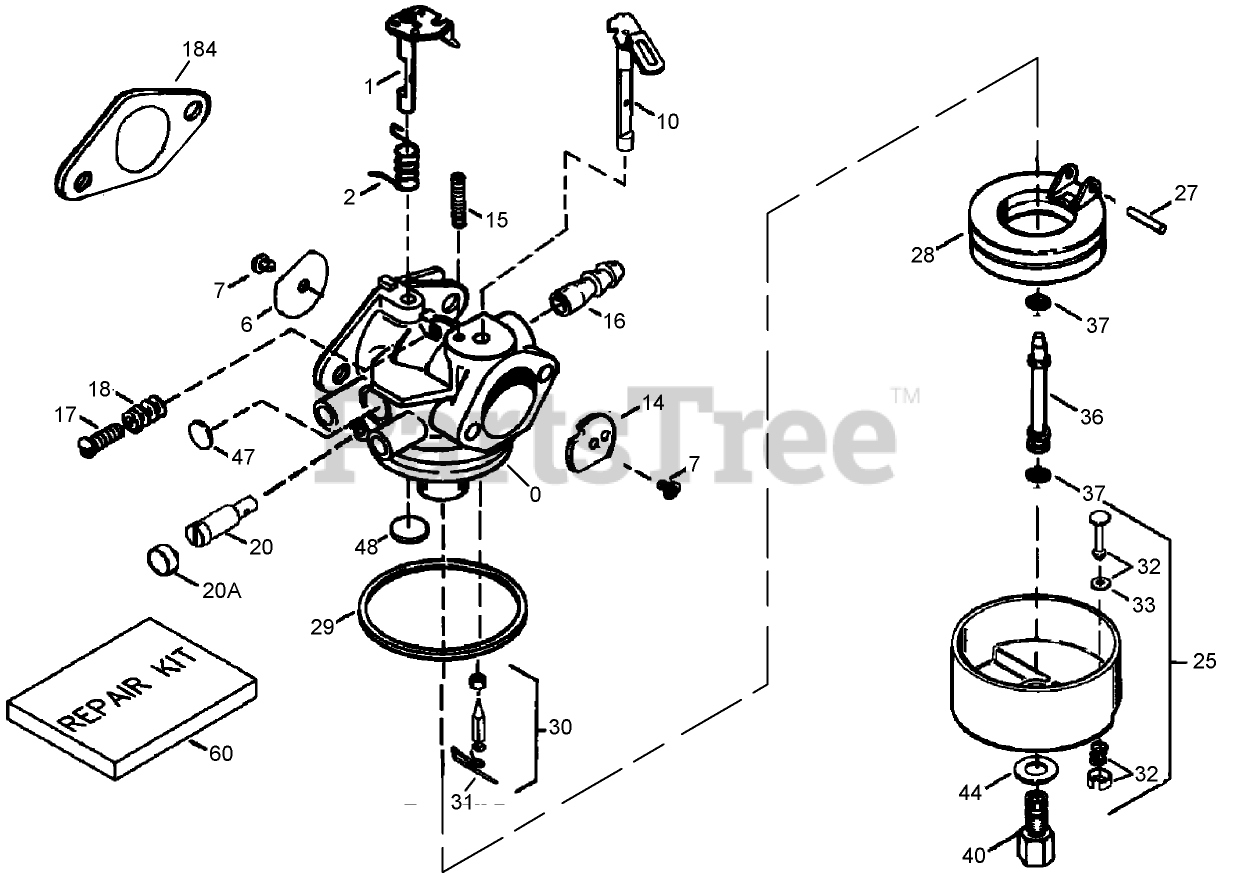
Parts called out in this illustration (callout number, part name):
1	Throttle Shaft and Lever ASM
2	Spring-Return, Throttle
6	Shutter-Throttle
7	Screw-Shutter
10	Choke Shaft and Lever ASM
14	Shutter-Choke
15	Spring-Positioning, Choke
16	Fitting-Fuel
17	Screw-Throttle Crack and Idle Speed
18	Spring-Tension
20	Screw-Restrictor, Idle
20A	Cap-Screw, Restrictor Idle
25	Float Bowl Asm. (Incl. Ref. # 32, 33)
27	Shaft-Float
28	Float (Plastic)
29	O Ring-Bowl, Float
30	Inlet Needle, Seat and Clip ASM (Includes 31)
31	Clip-Spring
32	Bowl Drain ASM
33	Gasket-Plunger, Drain
36	Tube-Nozzle
37	O-Ring
40	Nut-Bowl, High Speed
44	Washer-Bowl Nut
47	Plug-Welch, Idle Mixture Well
48	Plug-Welch, Atmospheric Vent
60	Carburetor Repair Kit
184	Gasket-Carburetor To Intake Pipe
